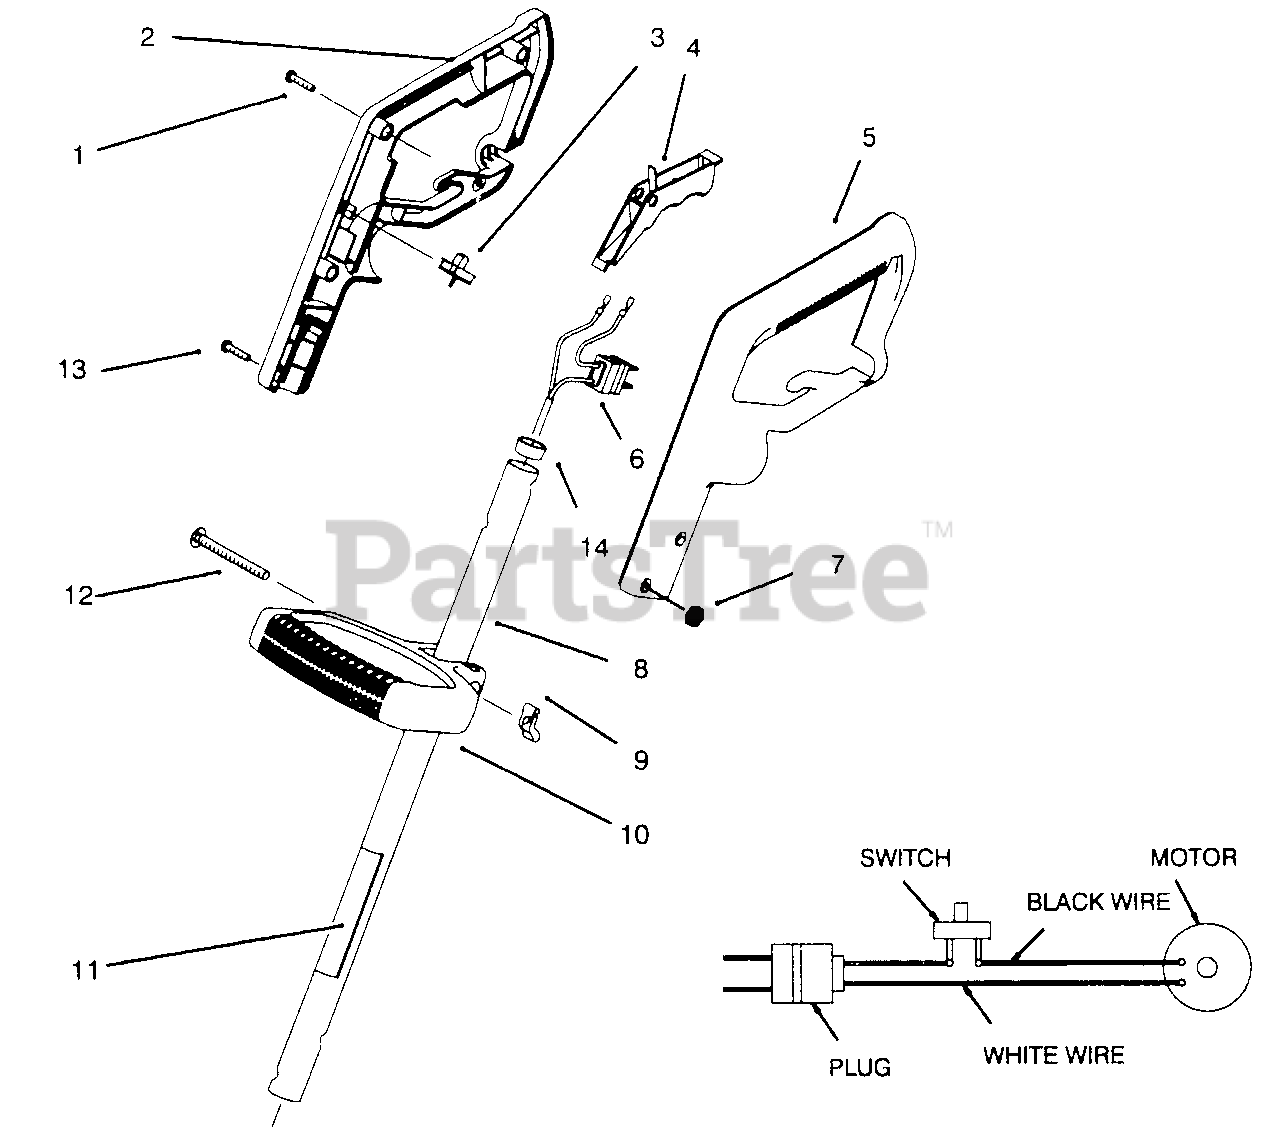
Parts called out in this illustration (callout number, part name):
1	Screw-Pan Hd. Tapping
2	Grip-Hand R.H.
3	Switch-Single Speed
5	Grip-Hand L.H.
6	Harness-Wire
7	Nut-Lock
8	Tube Assembly (Incl. Ref. #11)
10	Handle-Mid
11	Decal-Safety
12	Screw-Carriage
13	Screw-Pan Hd.
14	Bushing-Tube
